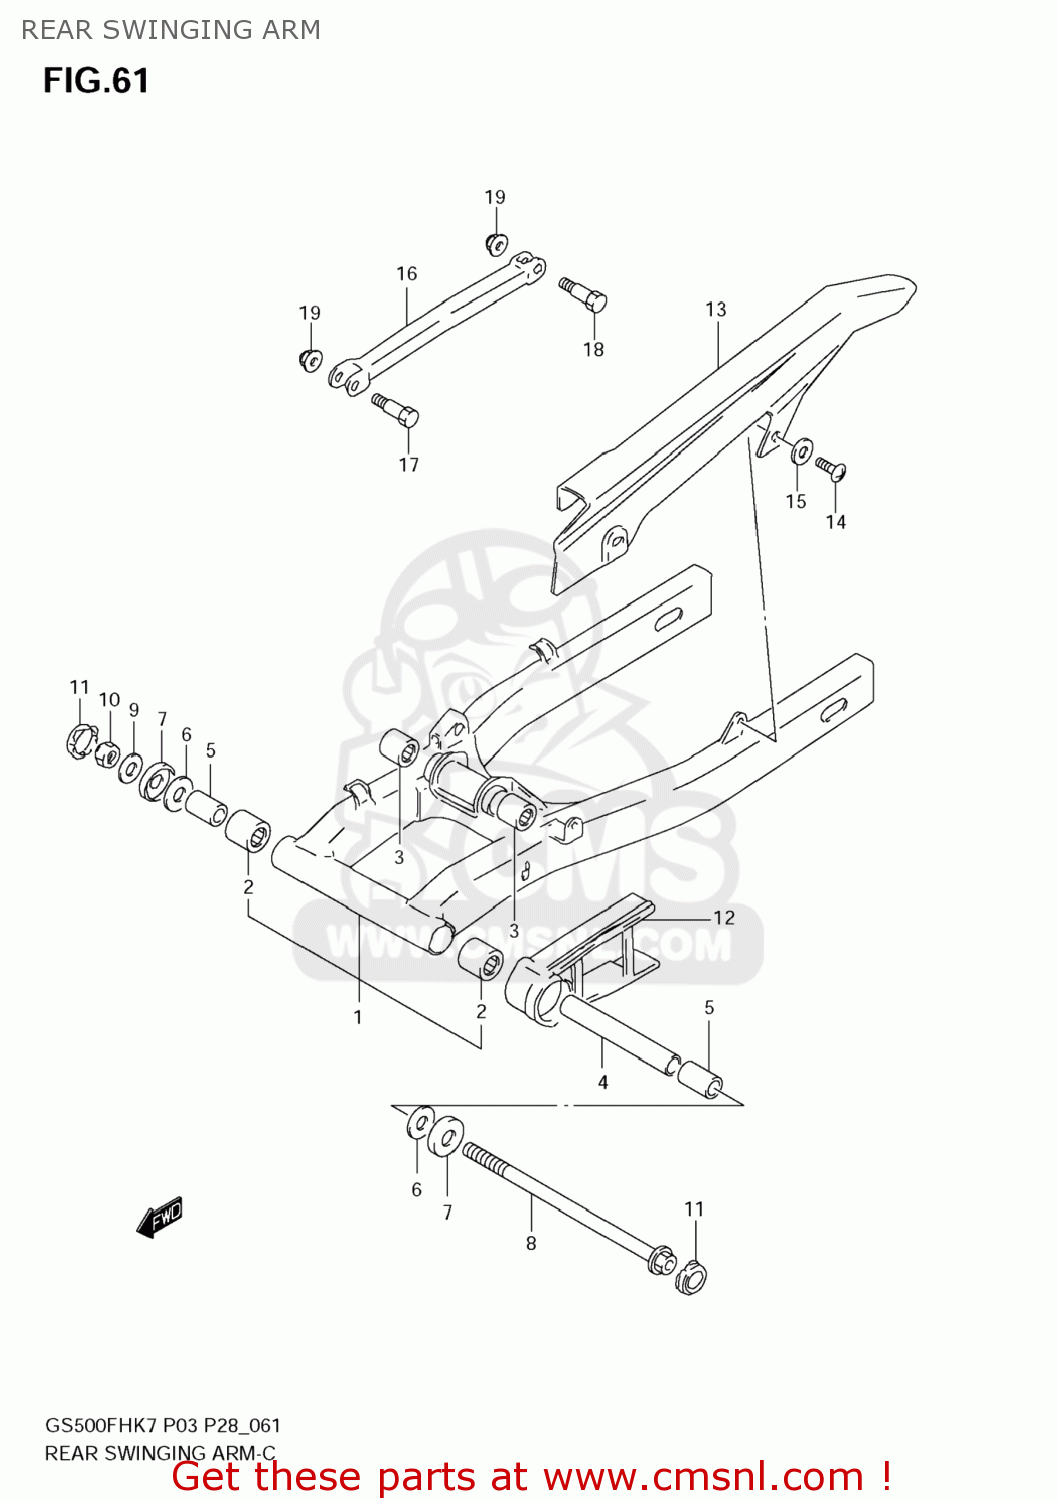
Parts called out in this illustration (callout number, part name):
2	BEARING(22X29X30)
3	BEARING(17X24X25)
4	SPACER,RR SWGARM PIVOT CTR
5	SPACER, PIVOT BEARING
6	WASHER(14.2X34X1)
7	CVR,RR SWGARM DUST SEAL(OD:40)
8	SHAFT,RR SWINGINGARM PIVOT
9	WASHER(14.5X29X2.3)
10	NUT
11	CAP,RR SWINGING ARM PIVOT
12	BUFFER,CHAIN TOUCH DEFENSE
13	CASE, CHAIN
14	SCREW
15	WASHER
16	TORQUELINK,RR
17	BOLT(10X41)
18	BOLT(10X34)
19	NUT
